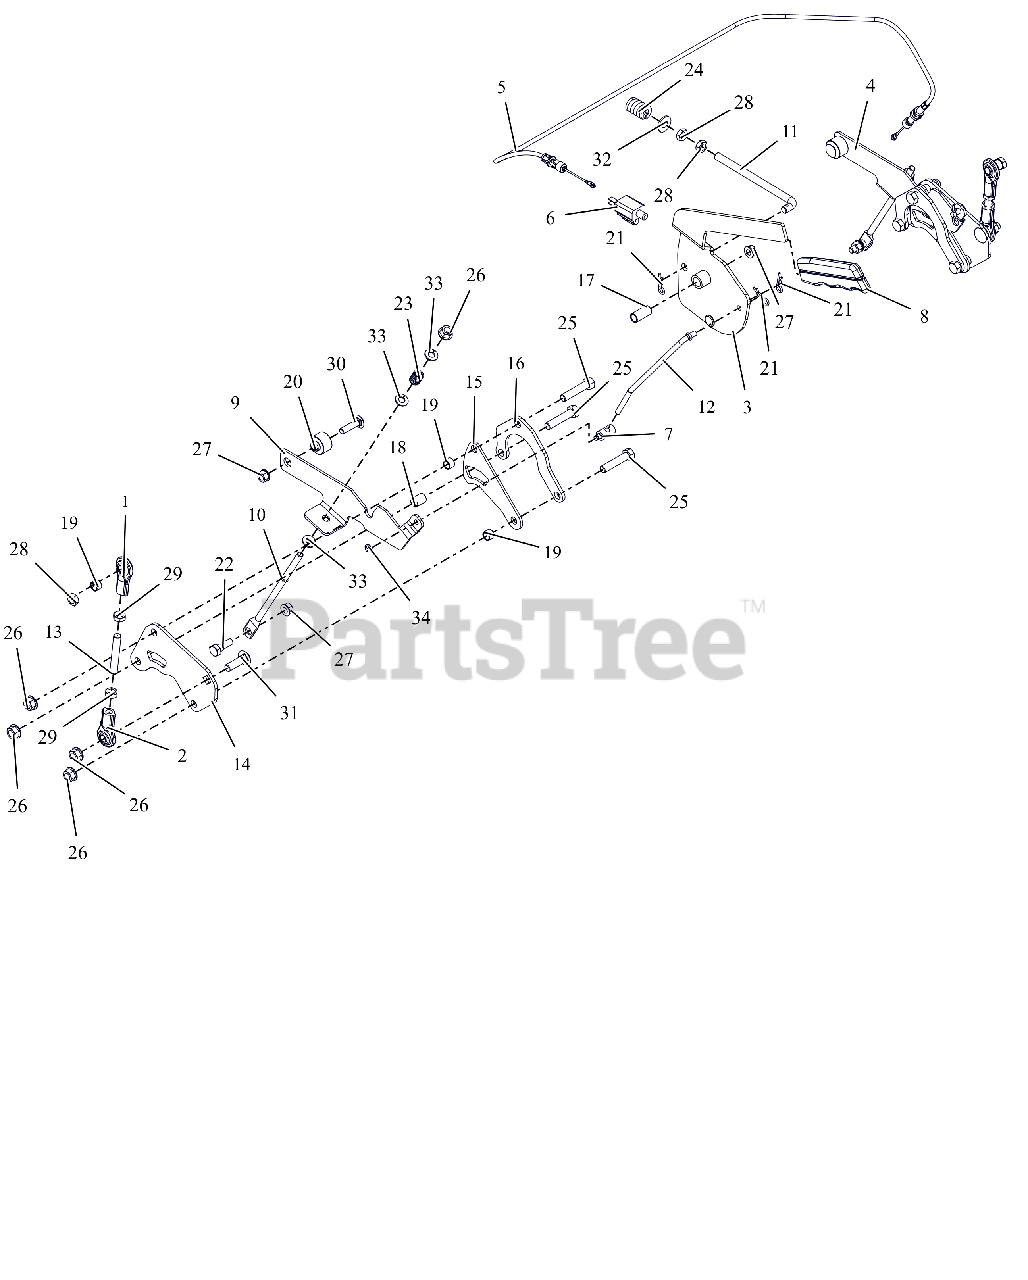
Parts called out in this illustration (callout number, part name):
1	ROD END, .38 RH
2	END, ROD-.38 LH
3	LEVER, PARKING BRAKE
4	ARM, BRAKE - LH (W/PIN)
5	CABLE, BRAKE
6	SWITCH, SINGLE POLE N.O.
7	TRUNION, 1/4-20
8	GRIP, PARKING BRAKE (YELLOW)
9	ARM, BRAKE-RH
10	ROD, LINK - TRANSMISSION BRAKE
11	ROD, OVER CENTER
12	ROD, BRAKE LINK
13	ROD, STEERING LINK
14	BRKT, TRANSAXLE STEERING
15	BRKT-SPACER
16	PLATE, REAR REINFORCING
17	BSHG-SLV .385X.500X1.045
18	SPCR, SLV .385X.500X.652
19	SPCR, SLV .385X.500X.350
20	SPCR, FLANGE
21	PIN, HAIR #213 .08X1.19 ZCC
22	BOLT,SHLDR .38X.25 -.31-18X.75
23	SPRING, COMPRESSION
24	SG-COMP .187X.56X1.62
25	BLT, HEX .38-16X1.75 G5 ZCC
26	NUT-LK-TOP-FLG .38-16 ZC120
27	NUT-LK-TOP-FLG .312-18 GF ZCC
28	NUT-JAM .375-16 G2 ZCC
29	NUT, HEX-JAM .38-24 ZCC
30	BLT, RHSSN.31-18X1.25 G5 ZCC
31	BLT,RHSSN .38-16X1.25 G5 ZCC
32	WSHR,FLT .375X.875X.083 ZCC
33	WSHR,FLT .344X.688X.065 ZCC
34	RG-RTNG-EXT .250X.025
